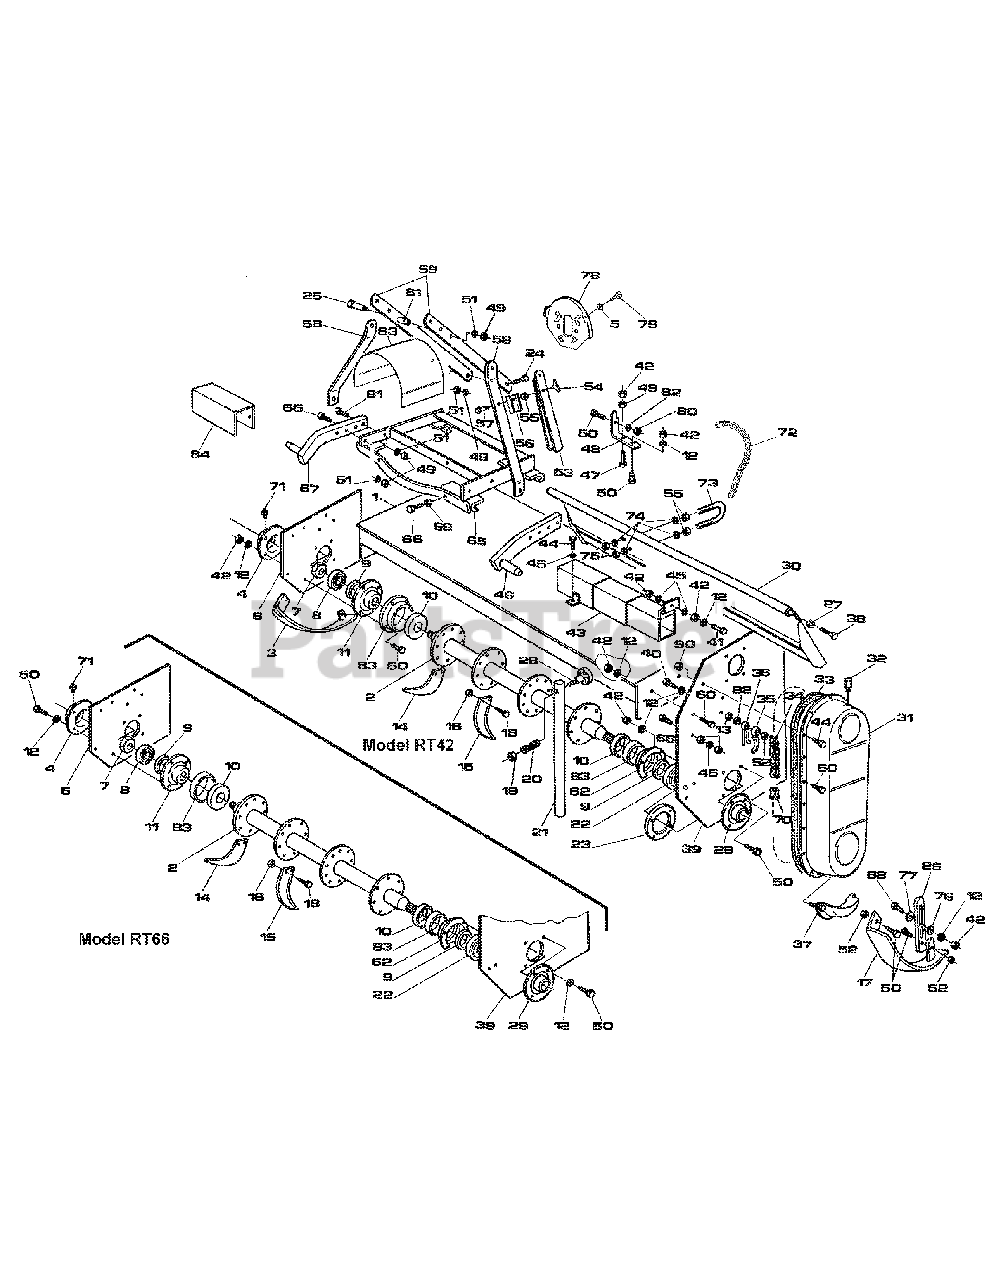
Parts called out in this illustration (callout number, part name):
3	Right skid
4	Right outer cover
5	Flat washer Ø6
6	Right side panel
7	Safety nut M30x1.5
8	Bearing 6306
9	Oil seal 40.60.10 RT42
9	Oil seal 40.56.8 RT66
10	Dirt shield
11	Cover RT42
11	Right rotor support RT66
12	Washer Ø10
13	Nut M10
14	Right C blade
15	Left C blade
16	Nut M12
17	Left skid
18	Bolt TE M12x30
19	Nut M14
20	Spring
22	Bearing 6307
23	Disk with holes
24	Bolt TE M12x90
25	Bolt TE M12x100
26	Serrated adjustment arm
27	Nut M16
28	Bolt TE M14x70
29	Left outer cover
30	Tail gate RT42
30	Tail gate RT66
31	Chain case cover
32	Breather cap
33	Gasket
34	Chain ASA 80sx36 RT42
34	Chain ASA 80HEx36 RT66
35	Chain tensioner
36	Spring
37	Chain case protection
38	Bolt TE M16x70
39	Left side panel
40	Bolt TE M10x60
41	Bolt TE M10x45
42	Nut M10
43	Protection RT42
43	Protection RT66
44	Bolt TE M10x20
45	Flat washer Ø10
46	Left lower hitch plate
47	Bolt TE M10x55
48	Chain hitch
49	Nut M12
50	Bolt TE M10x30
51	Washer Ø12
52	Nut M10
53	Ratchet arm
55	Nut M8
56	Locking cover
57	Bolt TE M8x50
58	Top hitch support
59	Top hitch arm
60	Bolt TE M10x25
61	Spacer
62	Cover RT42
62	Left rotor support RT66
63	PTO shaft protection
64	Right protection RT42
64	Right protection RT66
65	Side shift complete RT42
65	Side shift complete RT66
66	Bolt TE M12x60
67	Lower right hitch plate
68	Bolt TE M10x50
69	Nut M12
70	Chain link RT42
70	Chain link RT66
70	Inner chain link RT42
70	Inner chain link RT66
70	False chain link RT42
70	False chain link RT66
71	Grease fitting
72	Chain
73	U bolt
74	Flat washer Ø8
75	Nut M8
76	Washer
77	Threaded washer
78	Protection support
79	Bolt TC M6x12
80	Nut M10
81	Bolt TE M12x50
82	Flat washer Ø10
83	Dirt shield RT66
90	Nut M10
